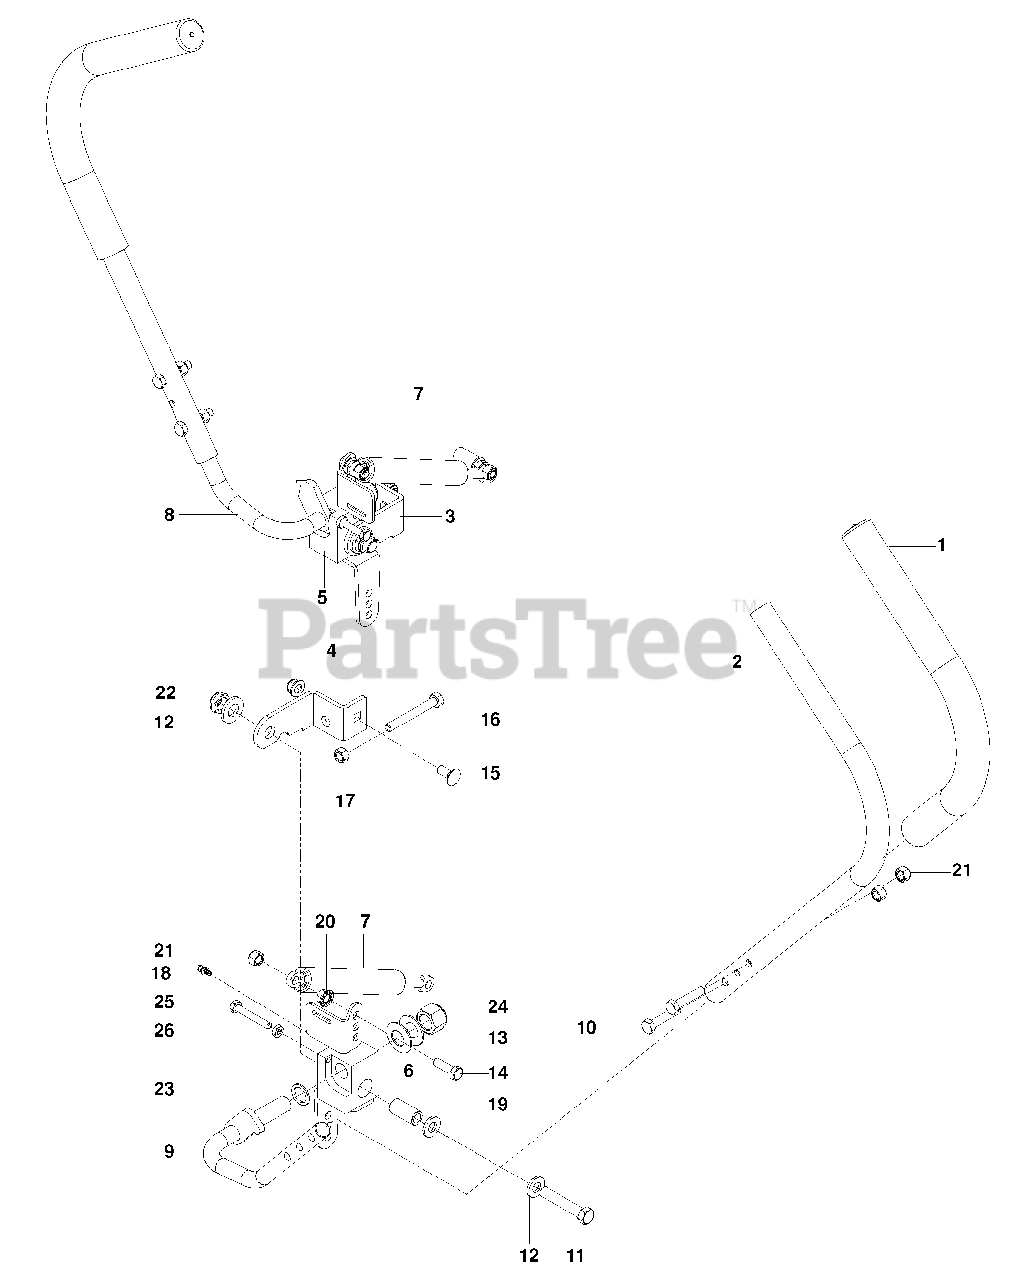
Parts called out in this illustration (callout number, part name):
2	LEVER, UPPER
3	STOP, STEER CNTRL RH
4	STOP, STEER CNTRL LH
8	LOWER LEVER, RH
9	LOWER LEVER, LH
10	HCS 5/16-18 x 1 1/2
11	HCS 1/2-13 x 2 3/4
12	WASHER 1/2 SAE
13	WASHER 5/8 BELLEVILLE
14	HCS 5/16-18 x 1
15	RHSNB 5/16-18 x 3/4
16	BOLT, HEX 5/16-18 x 2 1/2 TPBLT
17	NUT, 5/16-18 HEX
18	ZERK
19	BUSHING 1/2 ID x 3/4 OD
20	NUT 5/16-18 HEX WHIZLK
21	NUT 5/16-18 HEX NYLOC
22	NUT 1/2-13 JAM NYLOC GR 2
23	WASHER, SPECIAL
24	NUT 5/8-11 NYLOC
25	HCS 1/4-20 x 1 3/4
26	NUT 1/4-20 JAM
